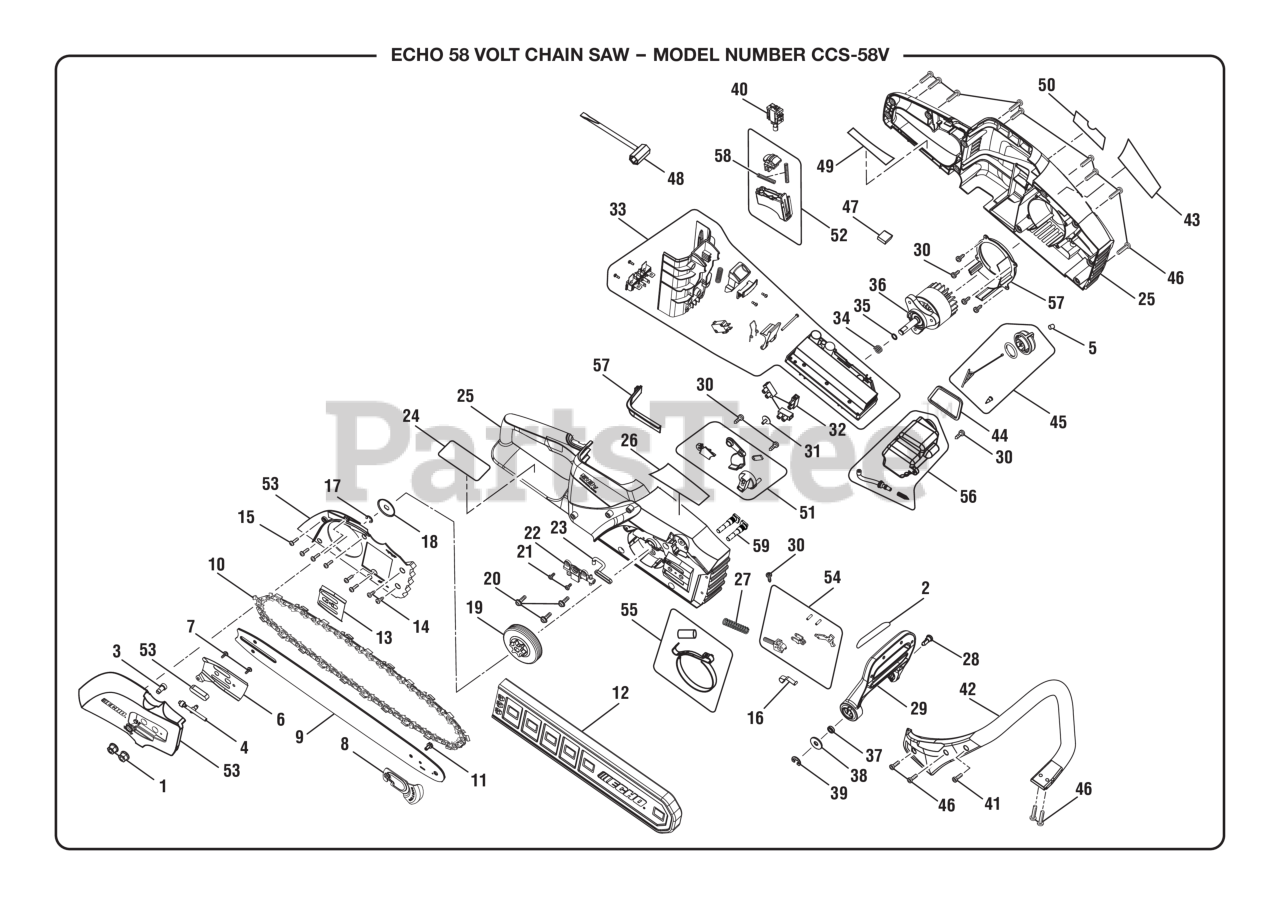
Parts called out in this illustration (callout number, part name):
1	Flange Nut (5/16-18, Hex Hd. for Guide Bar)
2	Chain Brake Label
3	Driving Adjustment Gear
4	Driven Adjustment Gear
5	Oil Cap Filter
6	Guide Plate
7	Screw (M4 x 12 mm, T20 Torx Hd.)
8	SAFE-T-TIP
9	Bar w/Graphics (Black 16 in. Bar)
10	Chain (16 in.)
11	SAFE-T-TIP (Screw & Washer)
12	Scabbard (16 in.)
13	Guide Plate Bar
14	Screw (10-14 x 13 mm, T25 Torx Ch. Hd. )
15	Screw (M4-18 x 12 mm, T20 Torx Pan Hd.)
18	Cap Washer
19	Sprocket w/Drum
20	Screw (M5 x 15 mm, T25 Torx Flange Hd.)
21	Screw (M4 x 9.5 mm, T20 Torx Truss Hd.)
22	Oil Pump Assembly
23	Outlet Tube
24	Icon Label
25	Housing Assembly
26	Warning Label (Right)
27	Chain Brake Spring
28	Screw (M5 x 10 mm, T25 Torx Hd. T.F.)
29	Front Handle Guard
30	Screw (M8 x 12 mm, T20 Torx Truss Hd.)
31	Screw (M4-18 x 10 mm, T20 Torx Washer Hd.)
32	TERMINAL
33	Battery Carriage and Circuit Board Assembly
34	Oil Pump Spring
36	Motor Assembly
37	Guard Bushing
38	Washer (ID6.8 x OD16 x 1.5t)
40	Variable Signal Switch
41	Screw (M5 x 25.5 mm, T25 Torx Rd. Hd.)
42	Front Handle
43	Warning Label (Left)
44	Oil Tank Gasket
45	Oil Cap Assembly
46	Screw (M5 x 17.5 mm, T20 Torx Pan Hd.)
47	Wrench Spring Plate
49	Data Label
50	Danger Label
51	Chain Brake Assembly
52	Trigger Assembly
53	Side Cover Assembly
54	Brake bend Connector Assembly
55	Brake Bend Assembly
56	Oil Tank Assembly
57	Volute & Wire Cover Assembly
58	Compression Spring
59	Guide Bar Bolt
